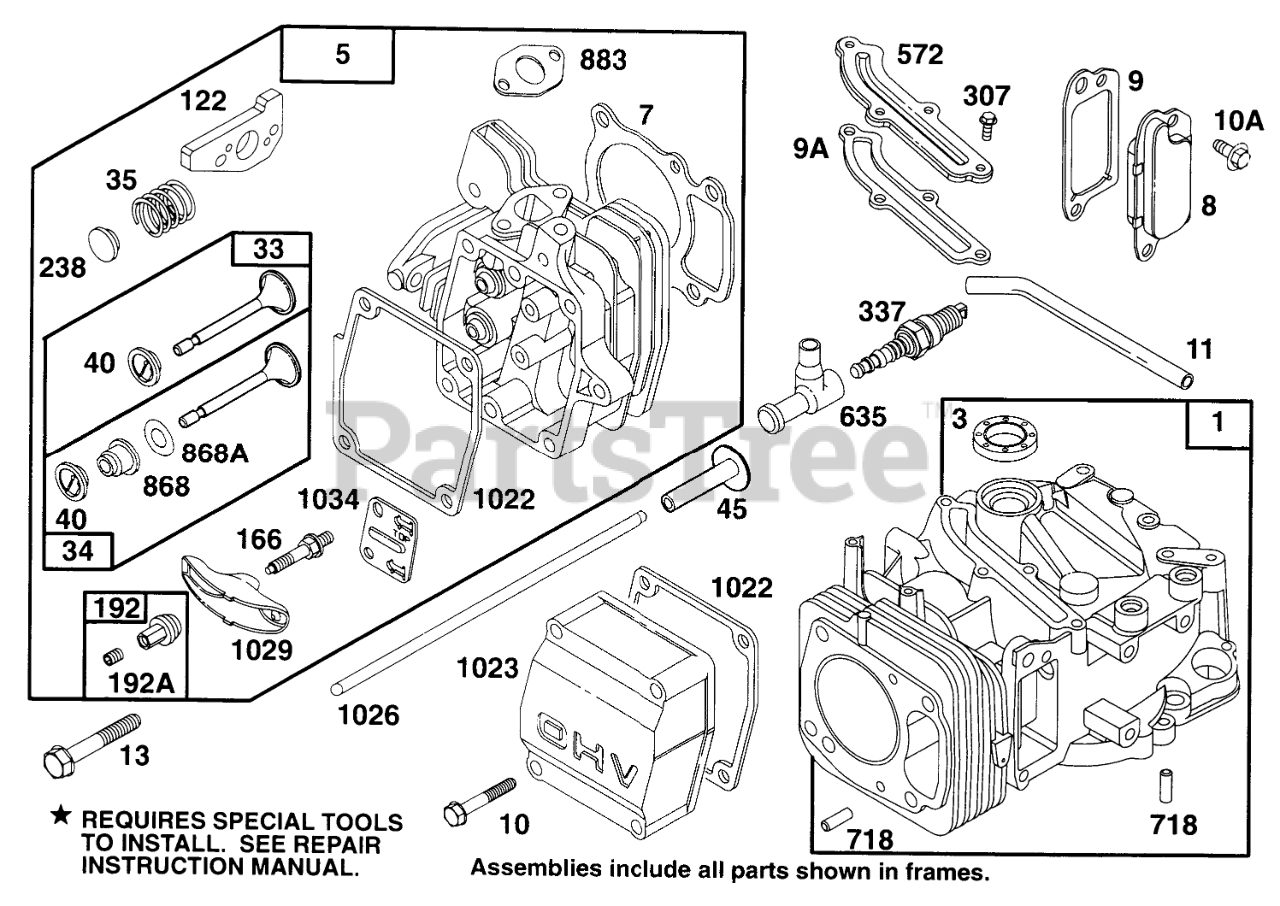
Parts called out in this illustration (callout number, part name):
1	CYLINDER ASSEMBLY
3	SEAL - OIL
5	CYLINDER HEAD
7	CYLINDER HEAD GASKET
8	Breather Assy
9	Gasket-Breather
9A	GASKET-BREATHER
10	HEX HEAD SCREW
10A	HEX HEAD SCREW
11	BREATHER TUBE
13	CYLINDER HEAD SCREW
33	EXHAUST VALVE
34	INTAKE VALVE
35	VALVE SPRING
40	SPRING RETAINER
45	VALVE TAPPET
122	ADAPTER ASSEMBLY
166	ROCKER ARM STUD
192	NUT - HEX SPECIAL
192A	Screw-Set
238	VALVE CAP
307	SCREW - SEM
337	PLUG-SPARK
572	BAFFLE - CYCLINDER
635	ELBOW-PLUG, SPARK
718	DOWEL - SLEEVE
868	SealAssy-Valve
868A	Seal-Valve
883	EXHAUST GASKET
1022	ROCKER COVER GASKET
1023	Cover-Valve
1026	PUSH ROD
1029	ROCKER ARM
1034	PUSH ROD GUIDE
